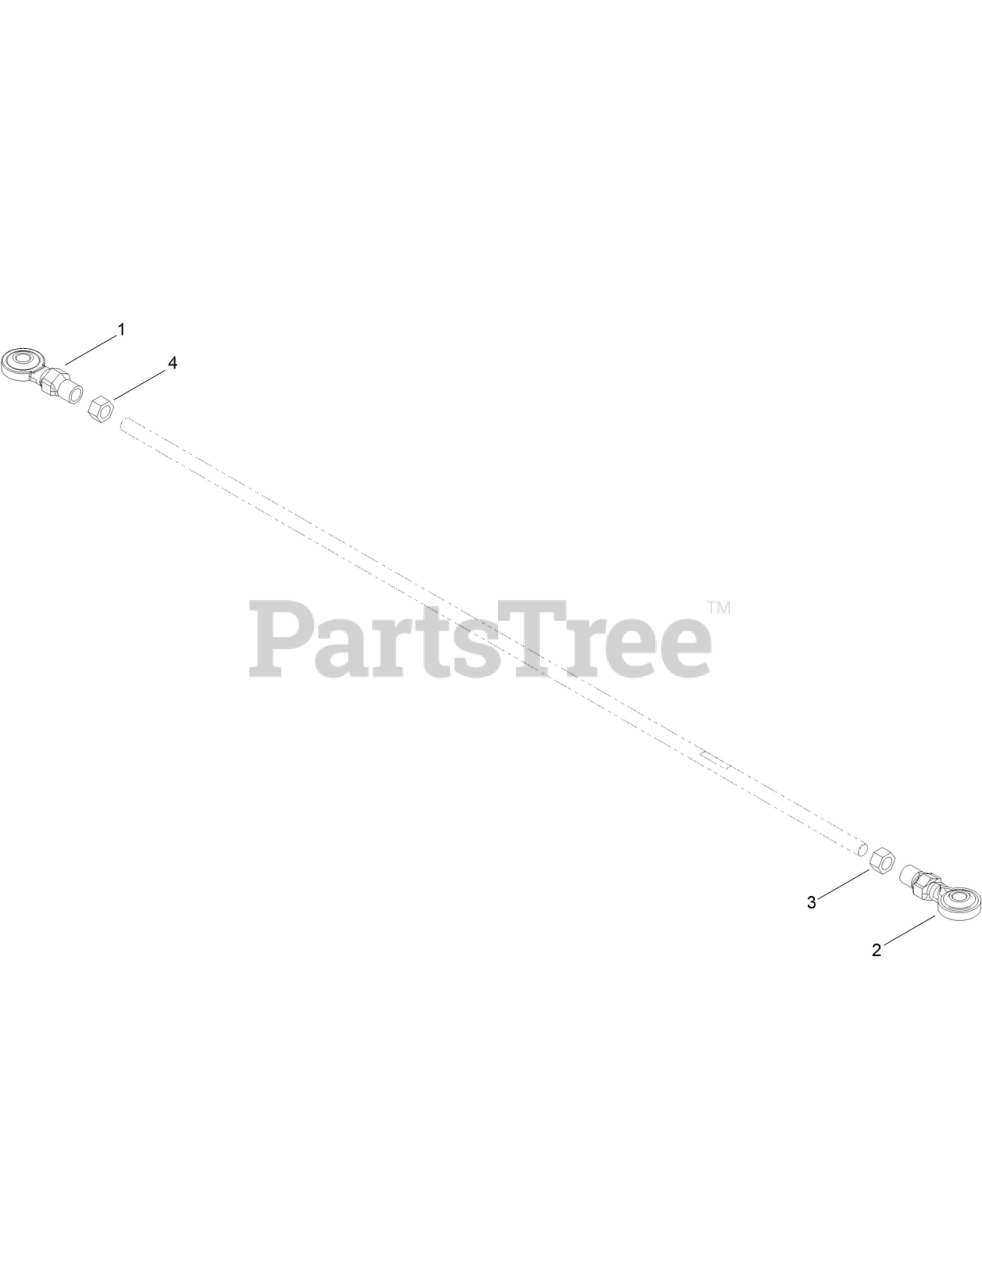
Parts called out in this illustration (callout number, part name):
1	BALL JOINT-LH
2	BALL JOINT-RH
3	NUT-HEX
4	NUT-HEX, LH
